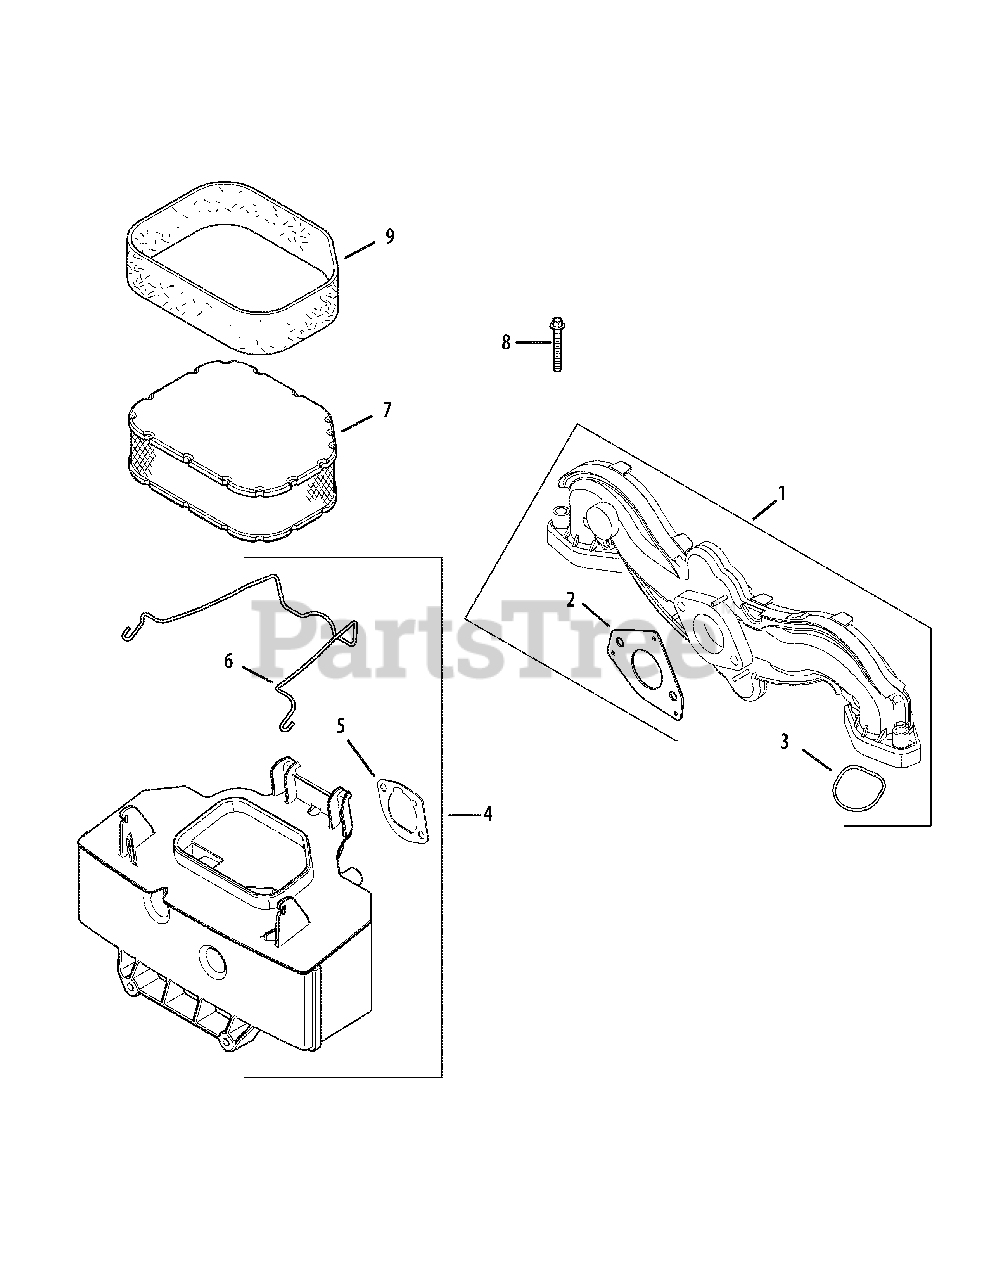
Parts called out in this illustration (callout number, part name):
1	Manifold, intake
2	Gasket, carburetor
3	O-Ring, intake port
4	Base, air cleaner
5	Gasket, air cleaner base
6	Latch, air cleaner element
7	Element, air cleaner
8	Screw, hex. flange M6x1.0x40
9	Pre-cleaner, element
